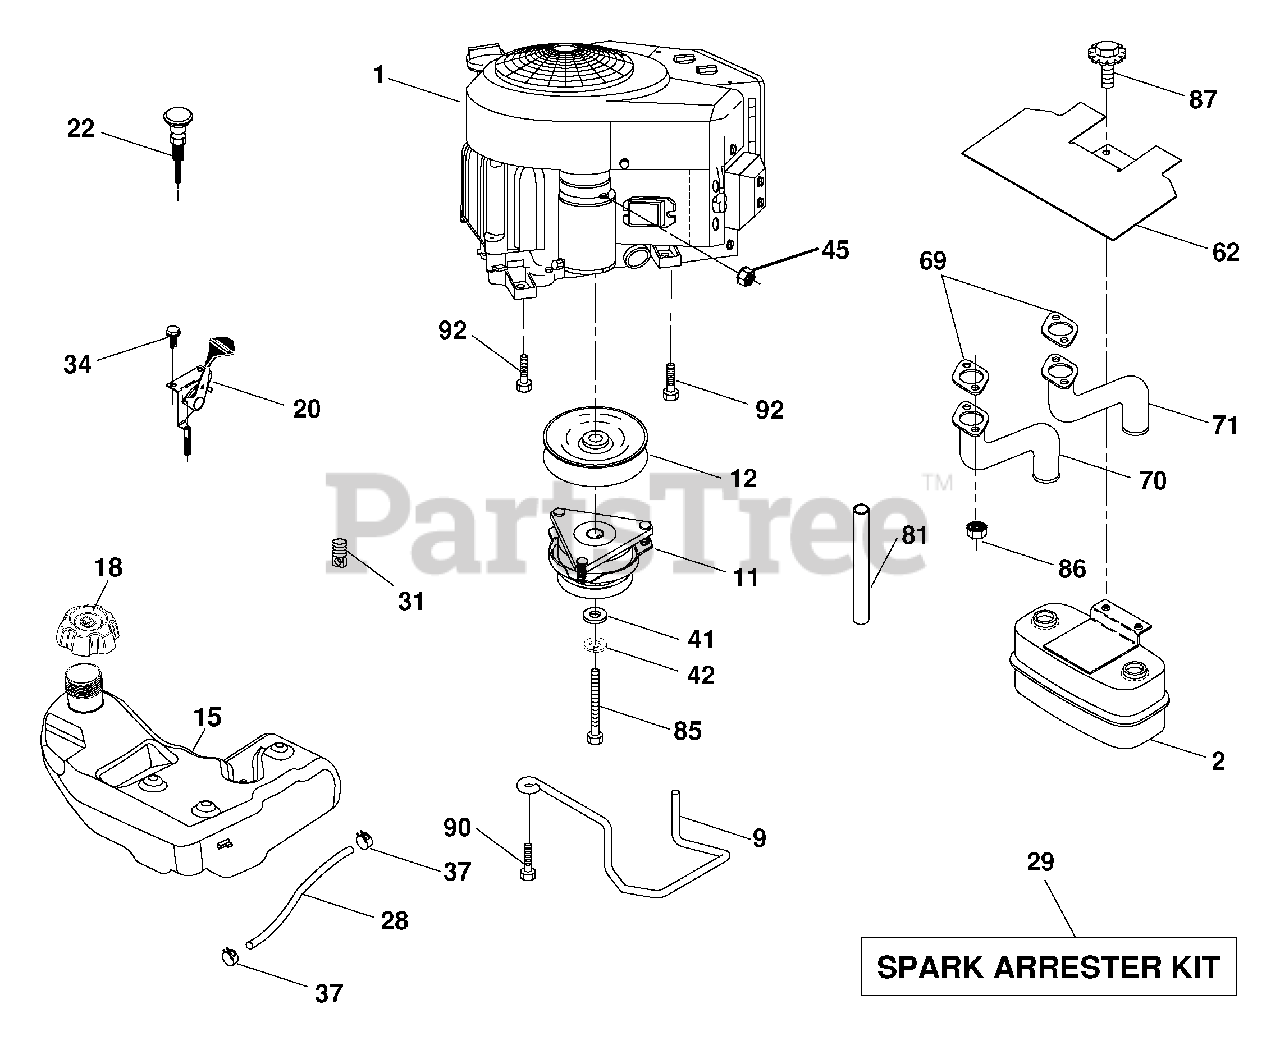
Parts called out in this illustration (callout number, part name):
1	Engine Kawa
9	Keeper Belt Engine
11	Clutch Electric
12	Pulley Engine
15	Tank Fuel 4.0
18	Cap Asm
20	Control Throttle
21	Screw 10 x 3/4 Single Lead Hex
22	Control Choke
28	Fuel Line
29	Spark Arrester Kit
31	Clip Push-In
37	Clamp Hose
41	Washer 1-1/2 OD x 15/32 ID x .250
42	Washer Lock 7/16
45	Nut Keps Hex 1/4-20 unc
62	Shield Heat Muffler
69	Gasket
70	Tube Exhaust LH
71	Tube Exhaust RH
81	Tube Drain Oil Easy
85	Bolt Hex 7/16-20 x 4 x Gr. 5-1.5
86	Nut Hex Flange Toplock M8-1.2
87	Bolt 5/16-18 unc x 1 w/Sems
90	Screw 3/8-16 x 1
92	Screw 3/8-16 x 1
